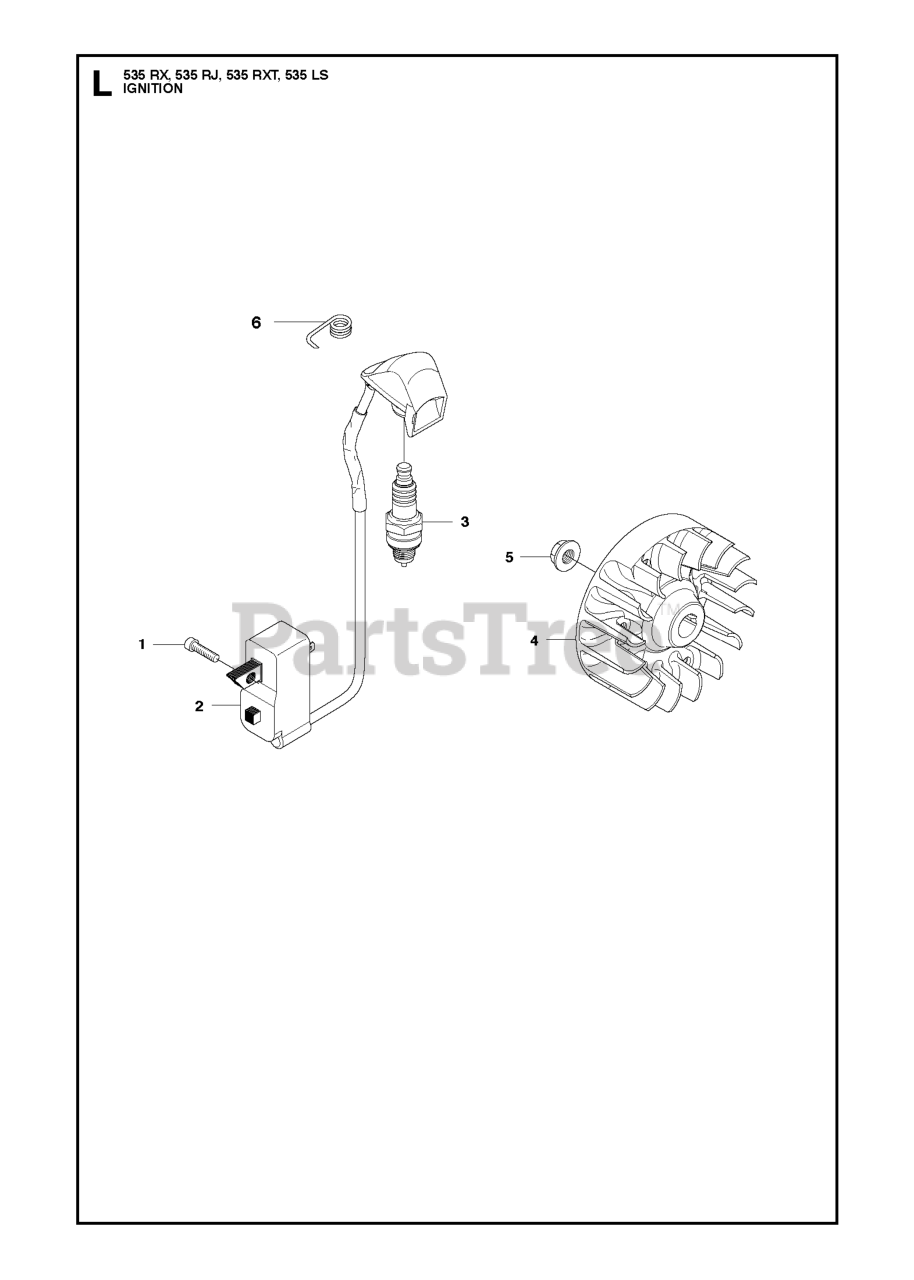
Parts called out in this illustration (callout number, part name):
2	IGNITION MODULE OPS
3	SPARK PLUG RCJ6Y NLA
4	FLYWHEEL
5	FLANGE NUT
